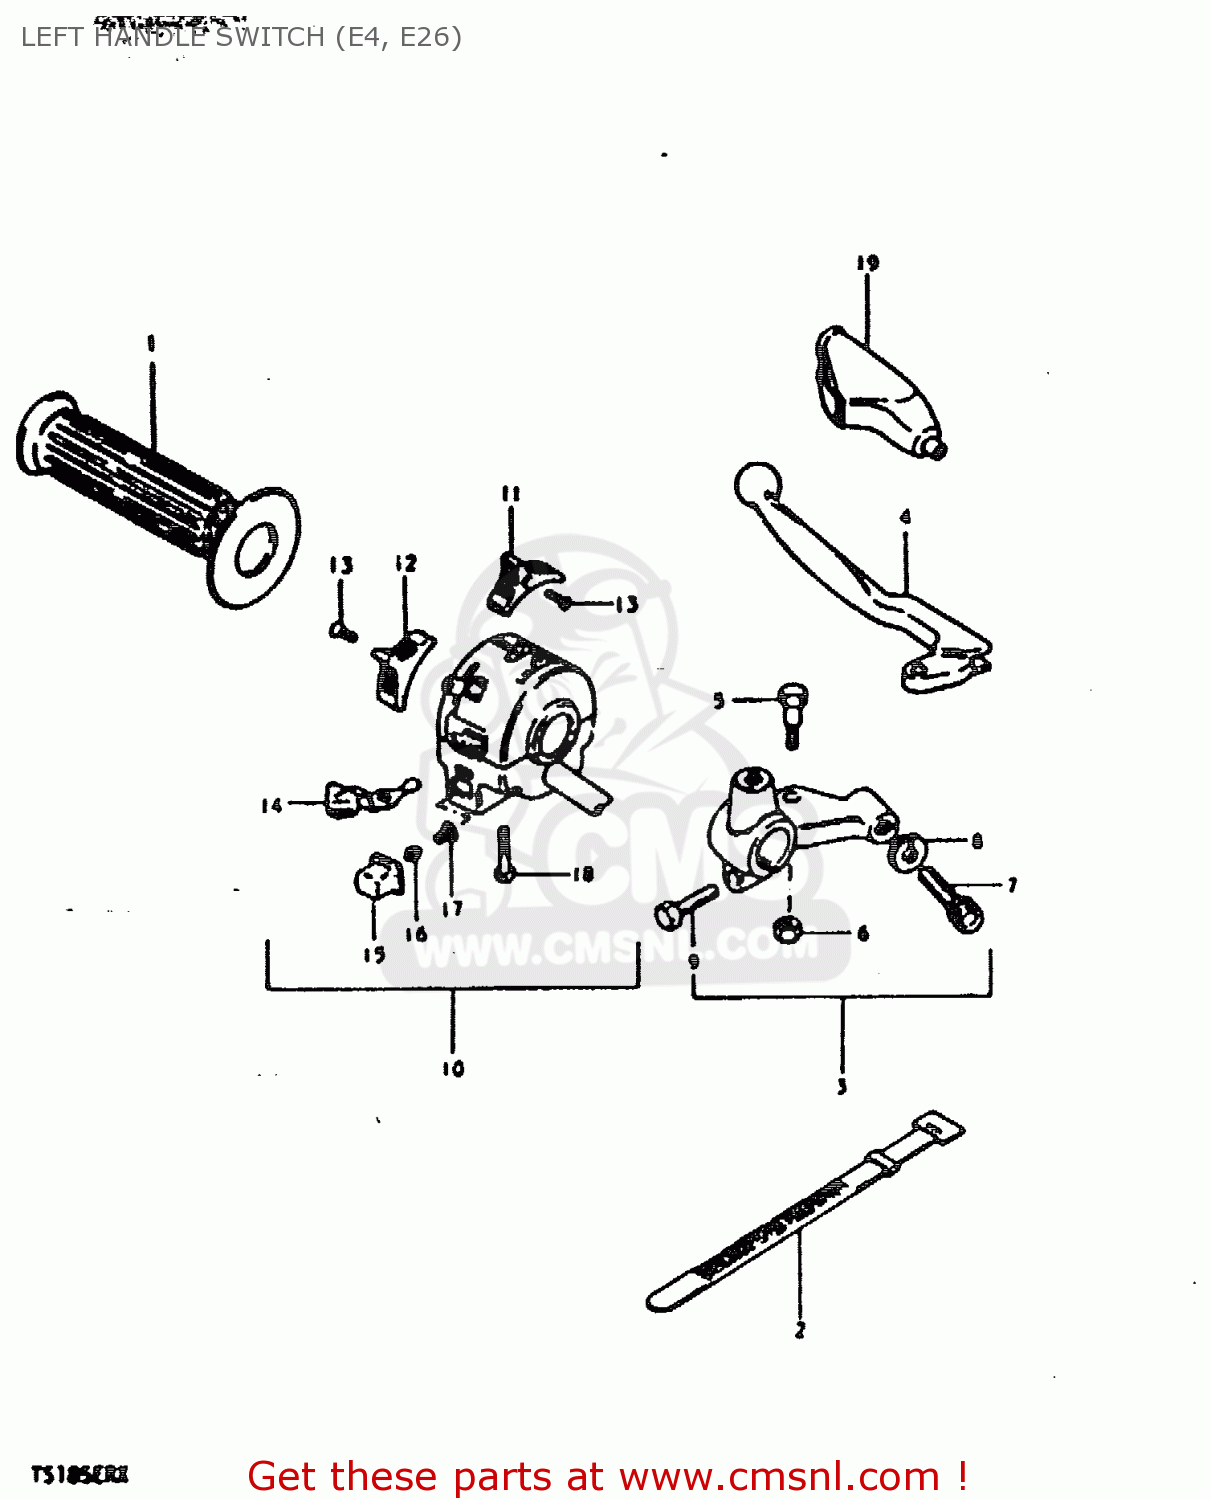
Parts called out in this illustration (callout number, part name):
1	GRIP,L
2	CLAMP(L:120)
3	LEVER ASSY,CLUTCH
4	LEVER,CLUTCH
5	BOLT,LEVER
6	NUT 6MM
7	ADJUSTER,CABLE
8	NUT,CABLE ADJUSTER
9	BOLT
10	SWITCH ASSY,HANDLE,L
11	KNOB,LIGHTING SWITCH
12	KNOB,DIMMER SWITCH
13	SCREW
14	KNOB,TURNSIGNAL
15	BUTTON,HORN
16	CONTACT
17	SPRING
18	SCREW
19	COVER,CLUTCH LEVER
